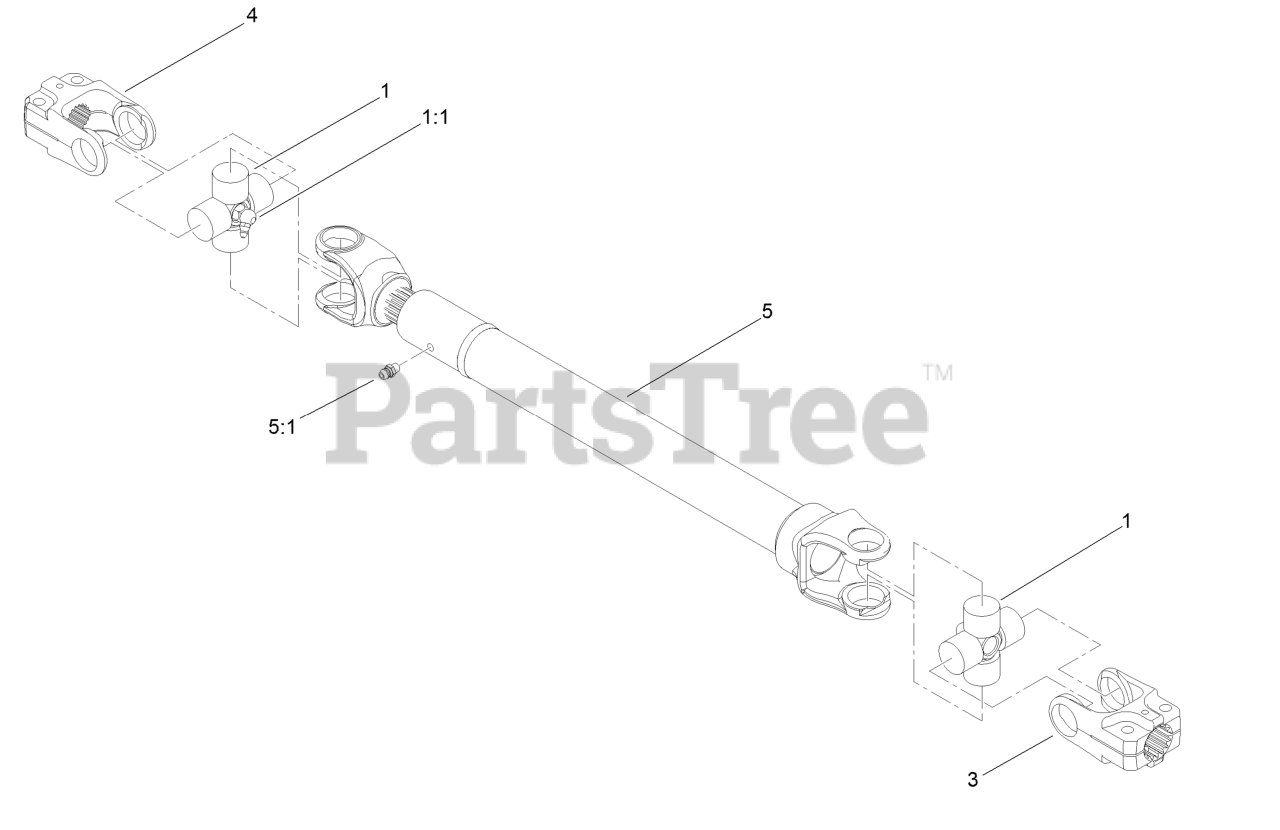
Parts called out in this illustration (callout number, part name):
1	Cross And Bearing Kit
1:1	Fitting-Grease
3	Yoke-End
4	Yoke-End
5	Tube-Yoke, Slip
5:1	Fitting-Grease
